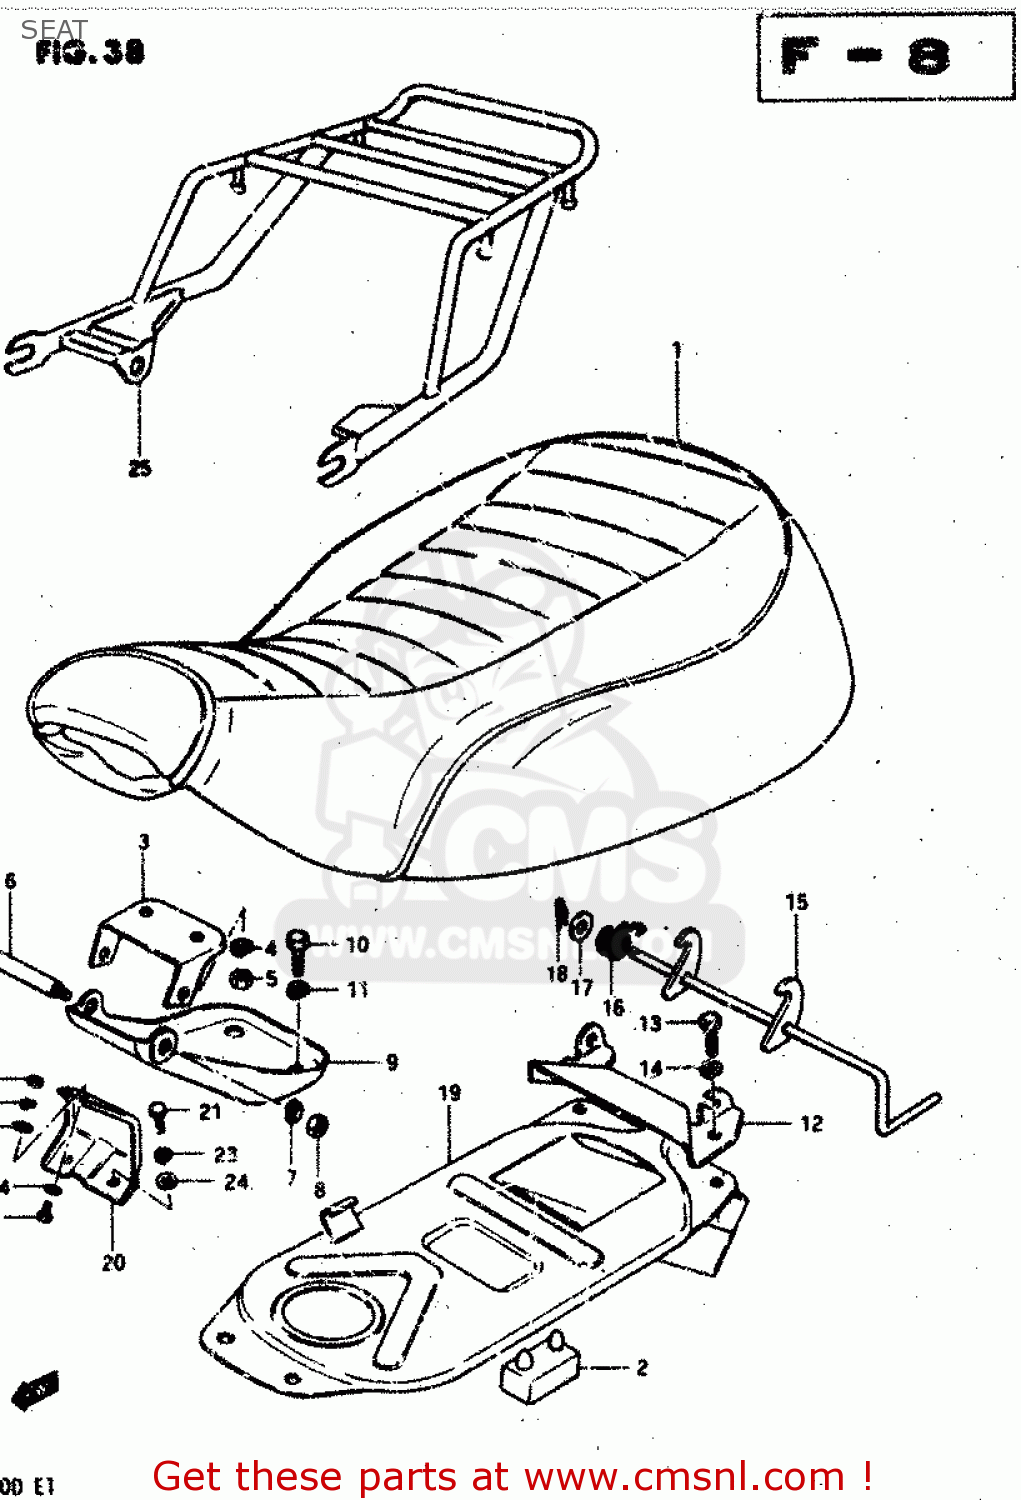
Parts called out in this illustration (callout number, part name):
1	SEAT ASSY (BLACK)
2	CUSHION
3	BRACKET,SEAT SUPPORT FR
4	LOCK WASHER
5	NUT
6	BOLT(6X71.5)
7	LOCK WASHER
8	NUT
9	BRACKET, LOWER
10	BOLT
11	LOCK WASHER
12	BRACKET,SEAT SUPPORT
13	BOLT, UPPER
14	LOCK WASHER
15	SHAFT,SEAT CLAMP
16	SPRING
17	WASHER
18	CLIP
19	PLATE, LOWER (BLACK)
20	BRACKET, FRONT (BLACK)
21	BOLT, UPPER
22	NUT
23	LOCK WASHER
24	WASHER
25	CARRIER,SPORT
